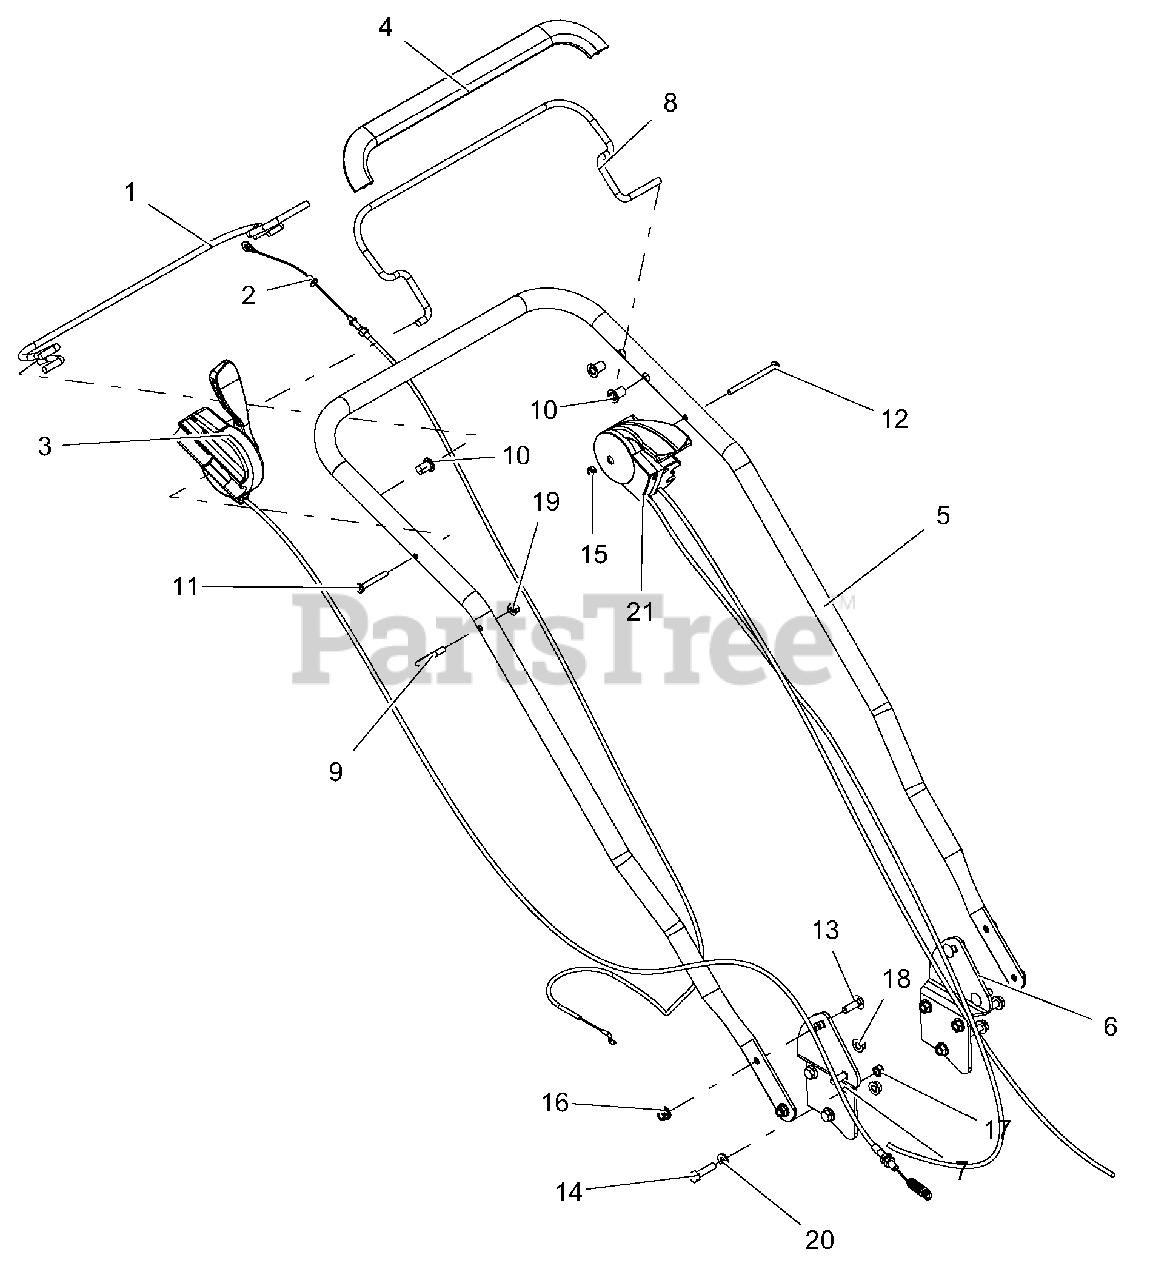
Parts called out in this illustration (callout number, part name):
1	OPC, LEVER
2	CLUTCH, CONTROL ASSEMBLY
3	ASM, BBC CONTROL
4	COVER, LEVER
5	HANDLEBAR, BENT
6	BRKT, HANDLEBAR -LEFT
7	BRKT, HANDLEBAR -RIGHT
8	LEVER, BBC
9	HOLDER, RECOIL ROPE (BLACK)
10	BSHG, LEVER
11	SCR, MACHINE M6-1X45 PANHD
12	SCR, MACHINE M6-1X80 PANHD
13	BLT-RDHDSQSHNK .31-18X1.00 G5 Y
14	BLT-HEX .31-18X1.25 GR5 YWZC
15	NUT-LK-NYL M6-1 YWZC
16	NUT-LK-NYL-FLG .31-18 YWZC
17	NUT-HEX .31-18 YWZC
18	NUT, LK-TOP-FLG .312-18 YWZC
19	NUT, LK-TOP-FLG .25-20 YWZC
20	WSHR-FL-STL.344X.688X.065YWZC
21	CONTROL, ASM SP SELECT & THROTTLE BBC
